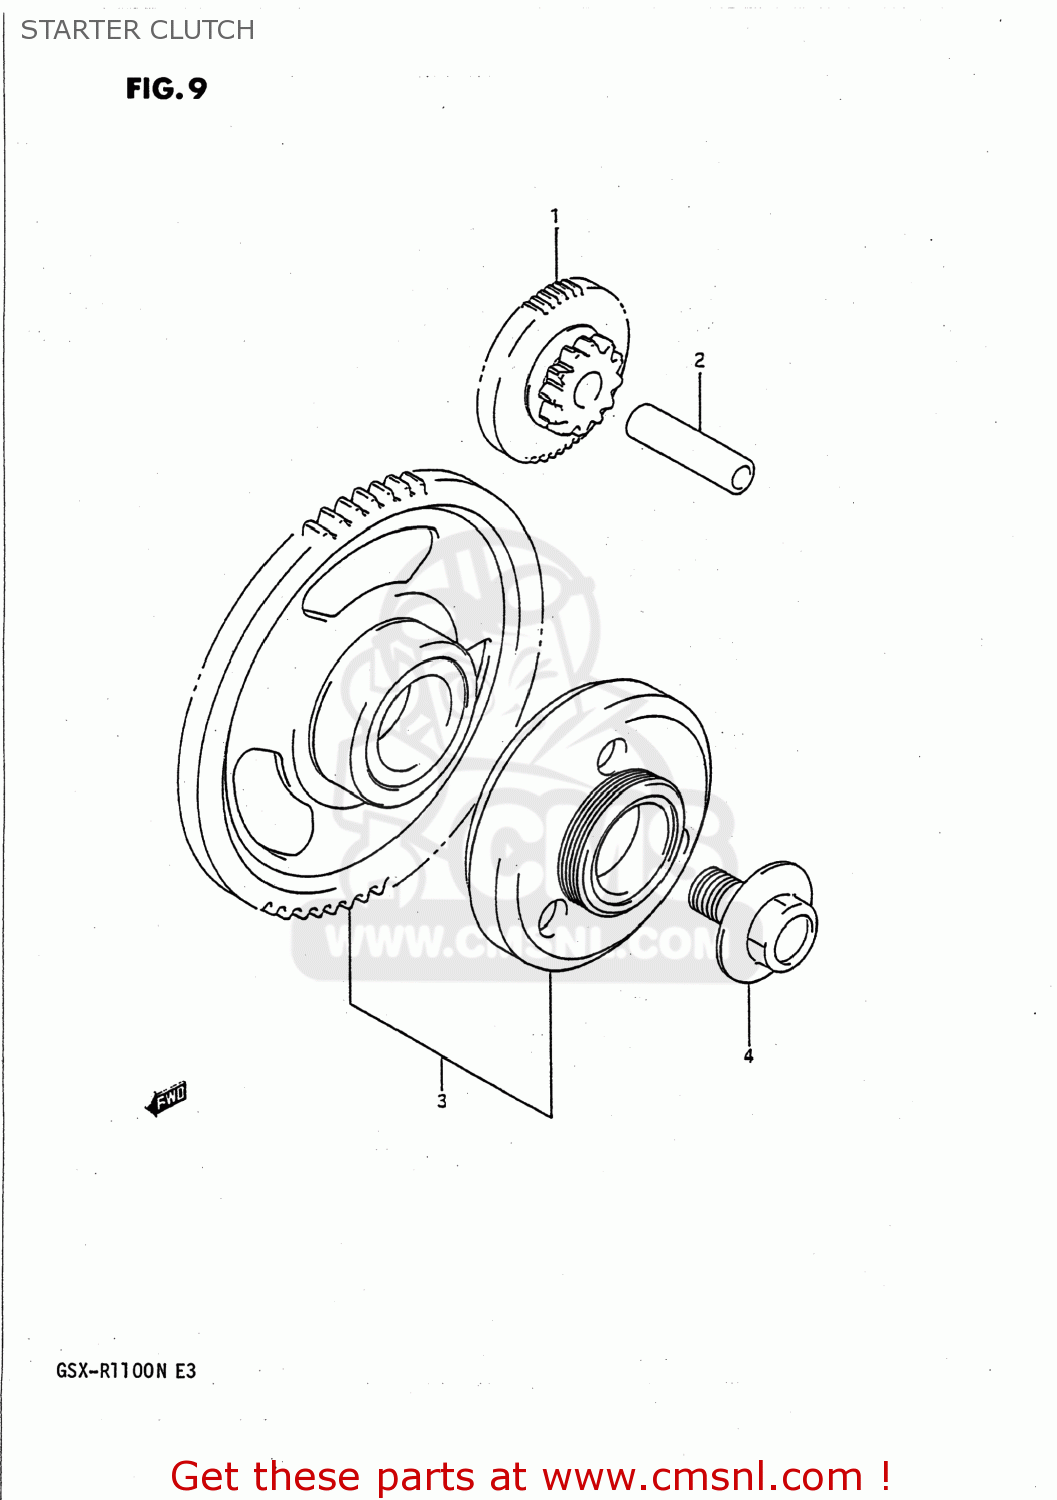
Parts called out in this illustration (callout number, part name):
1	GEAR,STARTER IDLE(NT:12,53)
2	PIN(7X11X42)
3	CLUTCH SET,STARTER
4	BOLT(14X21)
